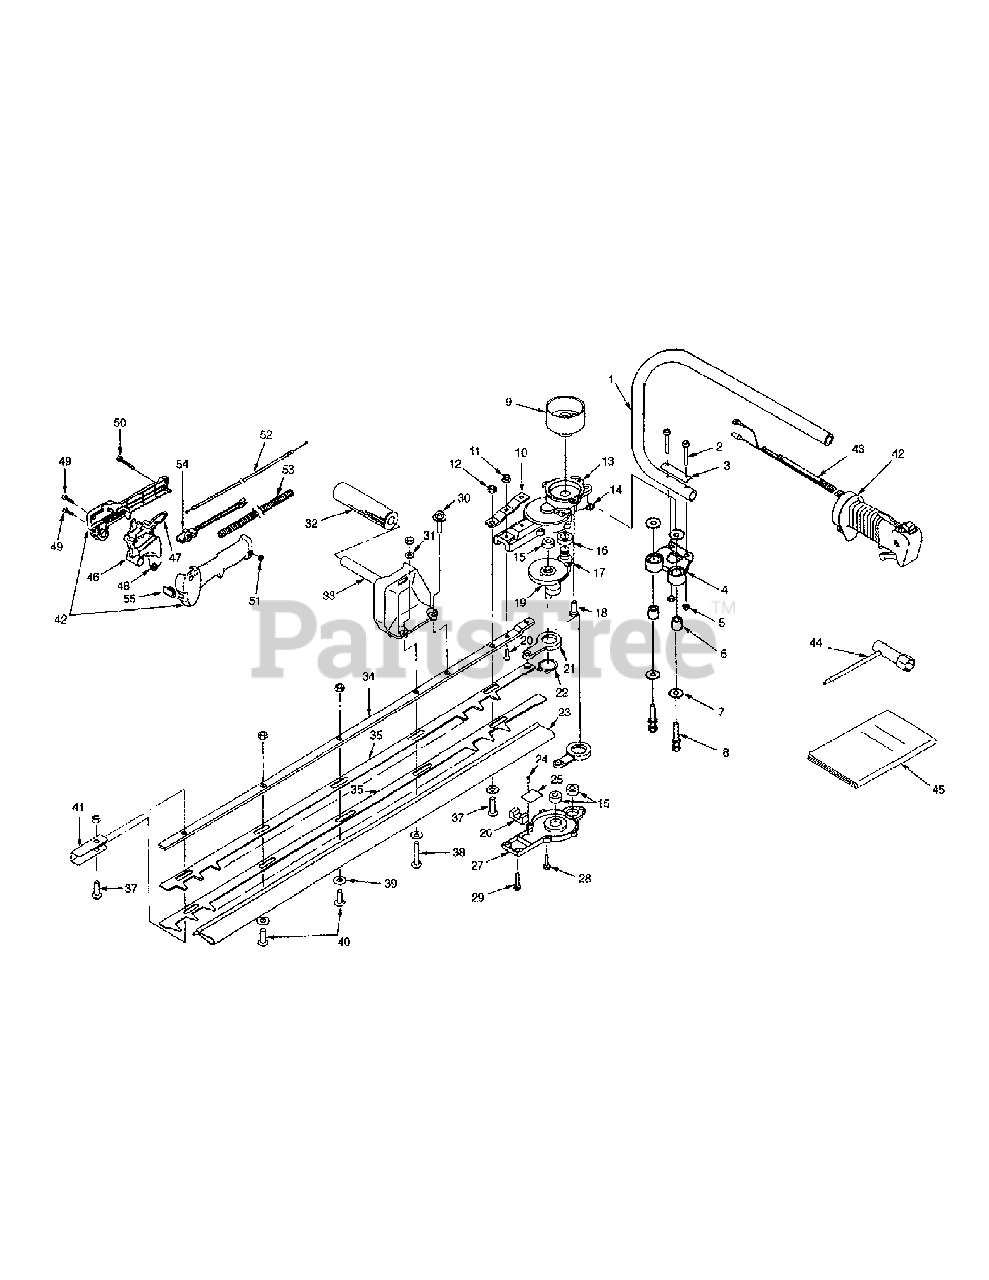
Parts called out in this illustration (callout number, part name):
3	Holder, Handle
4	Holder, Handle
9	Drum, Clutch
14	Nipples, Grease
15	Bearing, Ball, 6082
16	Bearing, Ball, 6001 LL
17	Gear, Pinion
20	Screw, M5x20
22	Snap Ring, S-26
23	Cover; Balde
42	Lever Assembly, Throttle
43	Wire Complete, Throttle
44	Wrench, Spanner Box 19
45	Manual, Operator's
46	Lever
50	Screw, M5x30
52	Wire Compl, Throttle
53	Hose
54	Stop, Switch
